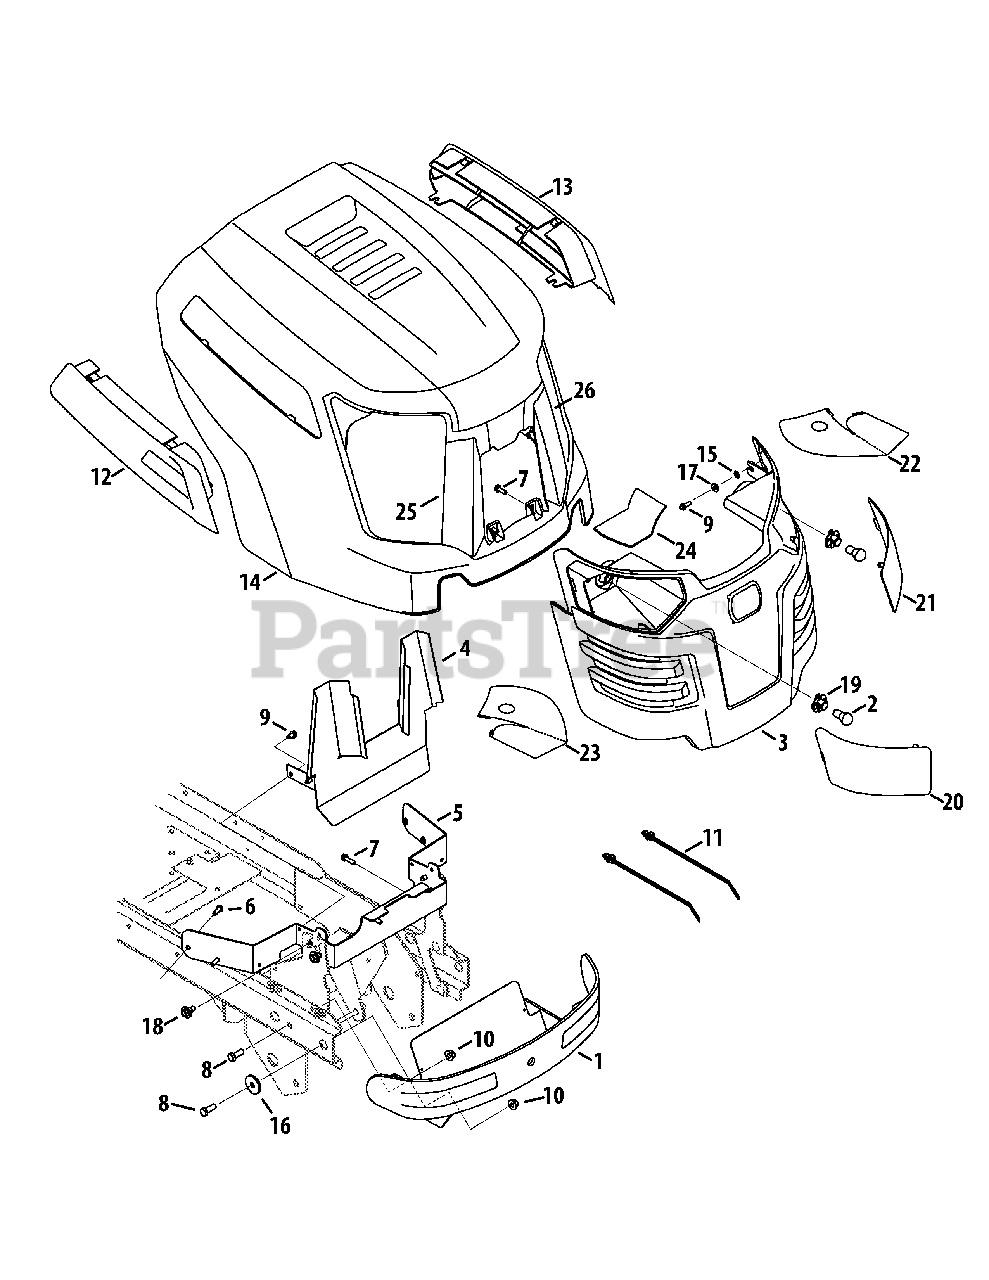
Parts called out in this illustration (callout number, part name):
1	Front Bumper Assembly
4	Heat Shield
5	Hood Pivot Bracket
6	Hex Washer Screw, 1/4 x .750
7	Hex Washer Screw, 5/16-14 x 1.00
8	Hex Screw, 3/8-16 x 1.00
9	Hex Washer Screw, 1/4-20 x 0.500
10	Flange Lock Nut, 3/8-16
11	Cable Tie, 7.5
12	RH Hood Scoop
13	LH Hood Scoop
14	Hood
15	Lock Washer, 1/4
16	Flat Washer, .390 x 1.500 x .134
17	Flat Washer, .271 x .630 x .065
18	Shoulder Screw, 5/16-18 x .43 x .29
19	1/4-turn Socket
20	RH Hood Lens
21	LH Hood Lens
22	Left Lens Reflector Label
23	Right Lens Reflector Label
24	Grill Insert
25	Hood Insert, LH
26	Hood Insert, RH
